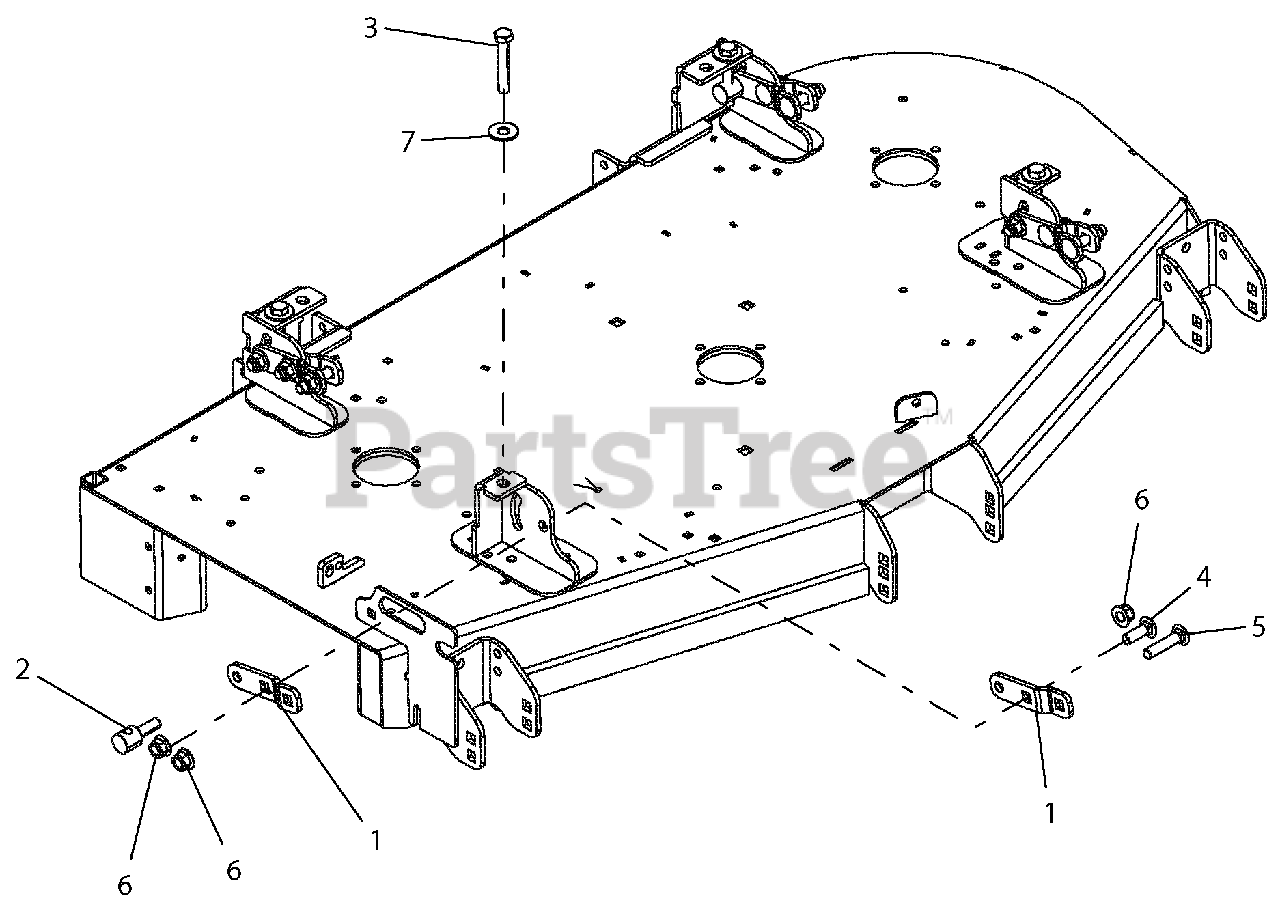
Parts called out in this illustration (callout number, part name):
1	BRKT, DECK LEVELING-BLACK
2	TRUNNION, .50-13
3	BLT, HEX .500-13 X 3.000 GR5 FTH YZ W/NYLON PATCH
4	BLT-RDHDSQNK .50-13X1.50 G5 YWZC
5	BLT-RDHDSQNK .50-13X2.25 G5 Y
6	NUT-LK-NYL-FLG .50-13 YWZC
7	WSHR-FL-STL.563X1.38X.109YWZC
